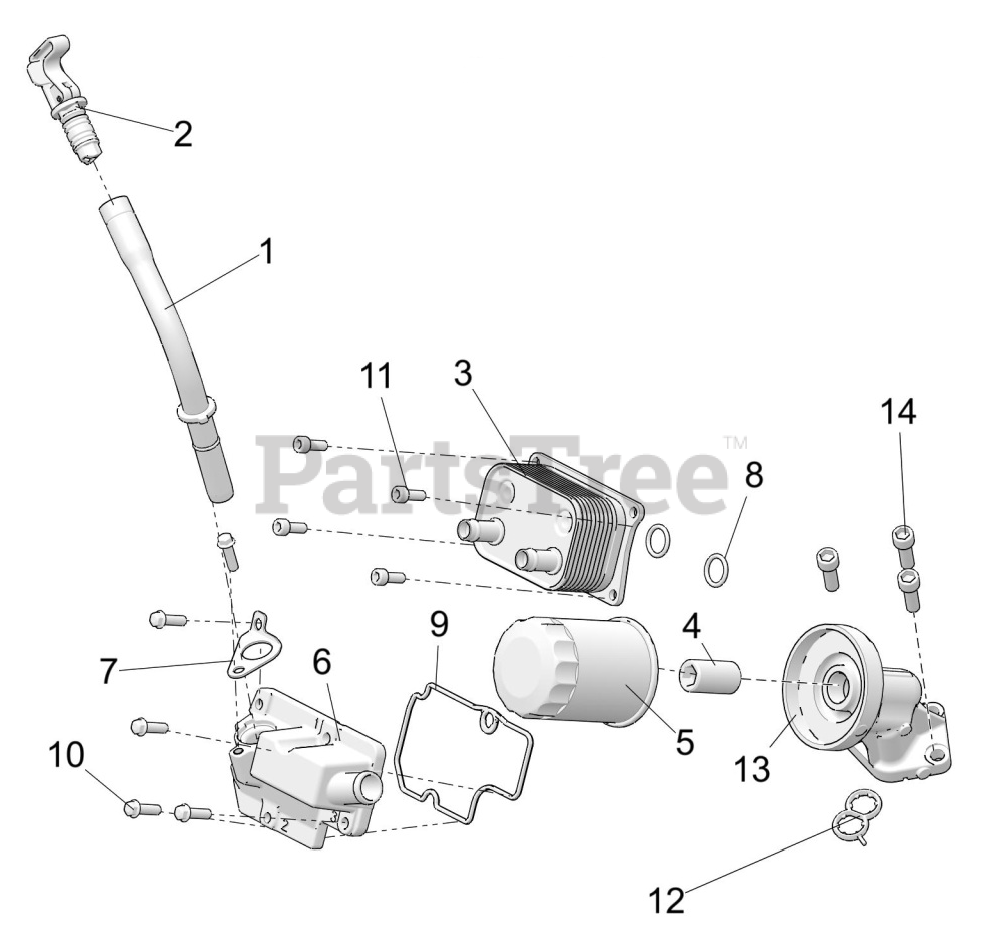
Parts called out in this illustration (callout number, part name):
1	ASM-OIL FILL TUBE
1	O-RING 12MM X 2MM
2	ASM-DIPSTICK
3	COOLER-OIL TO WATER-5
4	ADAPTER-FILTER-STRAIGHT
5	FILTER-OIL-10 MICRON-(12)
6	COVER, BREATHER
7	BRACKET, TUBE, OIL FILL, LOWER
8	O-RING-.612X.818X.103
9	SEAL-COVER-BREATHER
10	SCR-M6X20-HXFLG-0600214
11	SCR-SH-M6X1.0X16 8.8 ZPY D2O4
12	SEAL-FILTER ADAPTER-3 HOLE
13	ADAPTER-OIL FILTER- MACH
14	SCR-SH-M8X1.25X25 8.8 ZPC NYL
